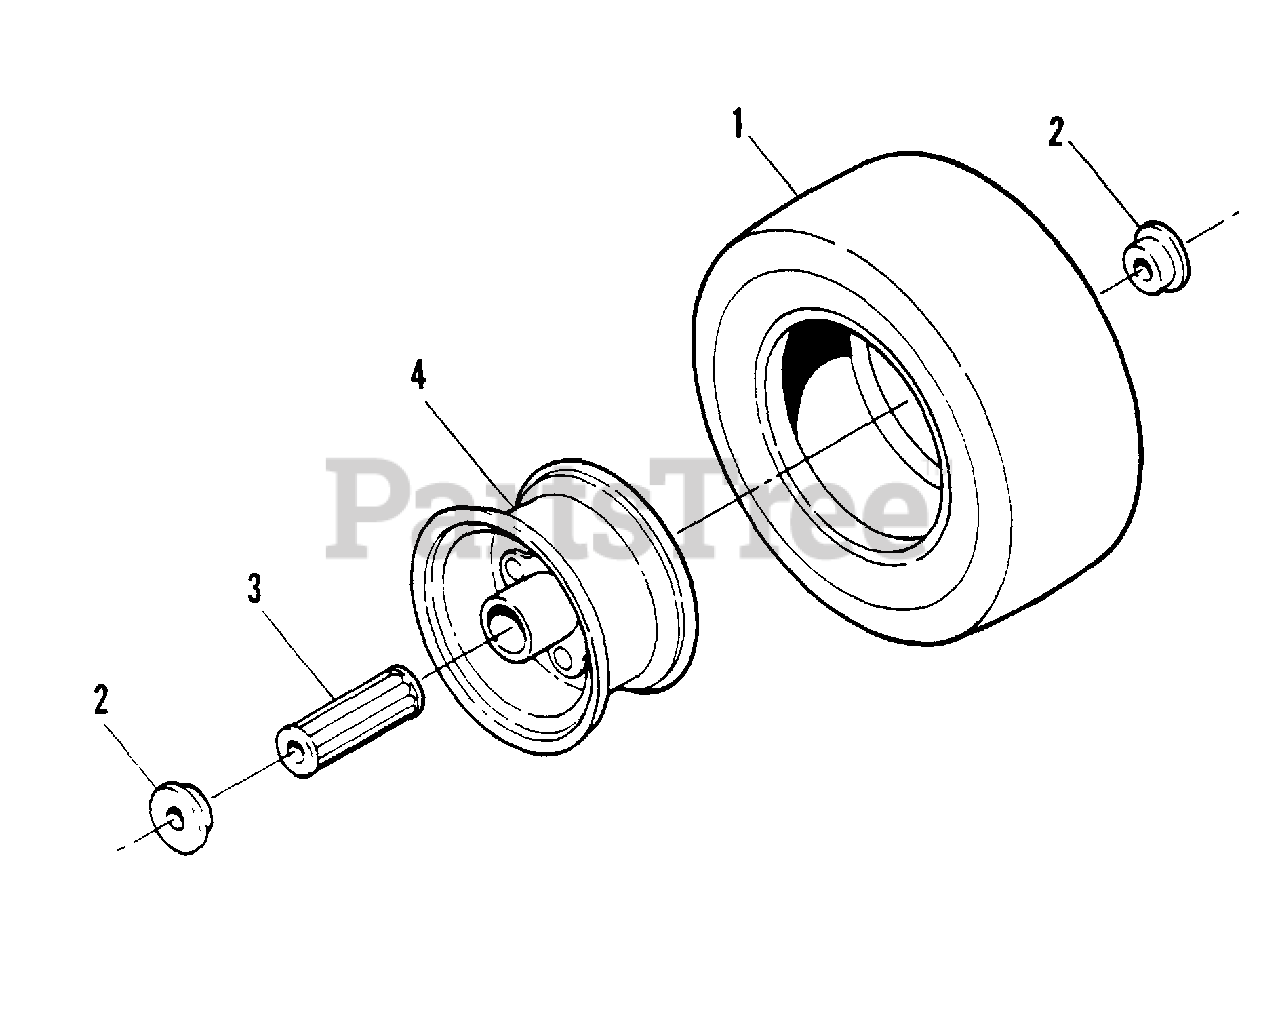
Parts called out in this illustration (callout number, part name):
1	TIRE, 9 x 3.50 - 4
2	RETAINER, Flanged
3	ROLLER BEARING
4	WHEEL ASSEMBLY
